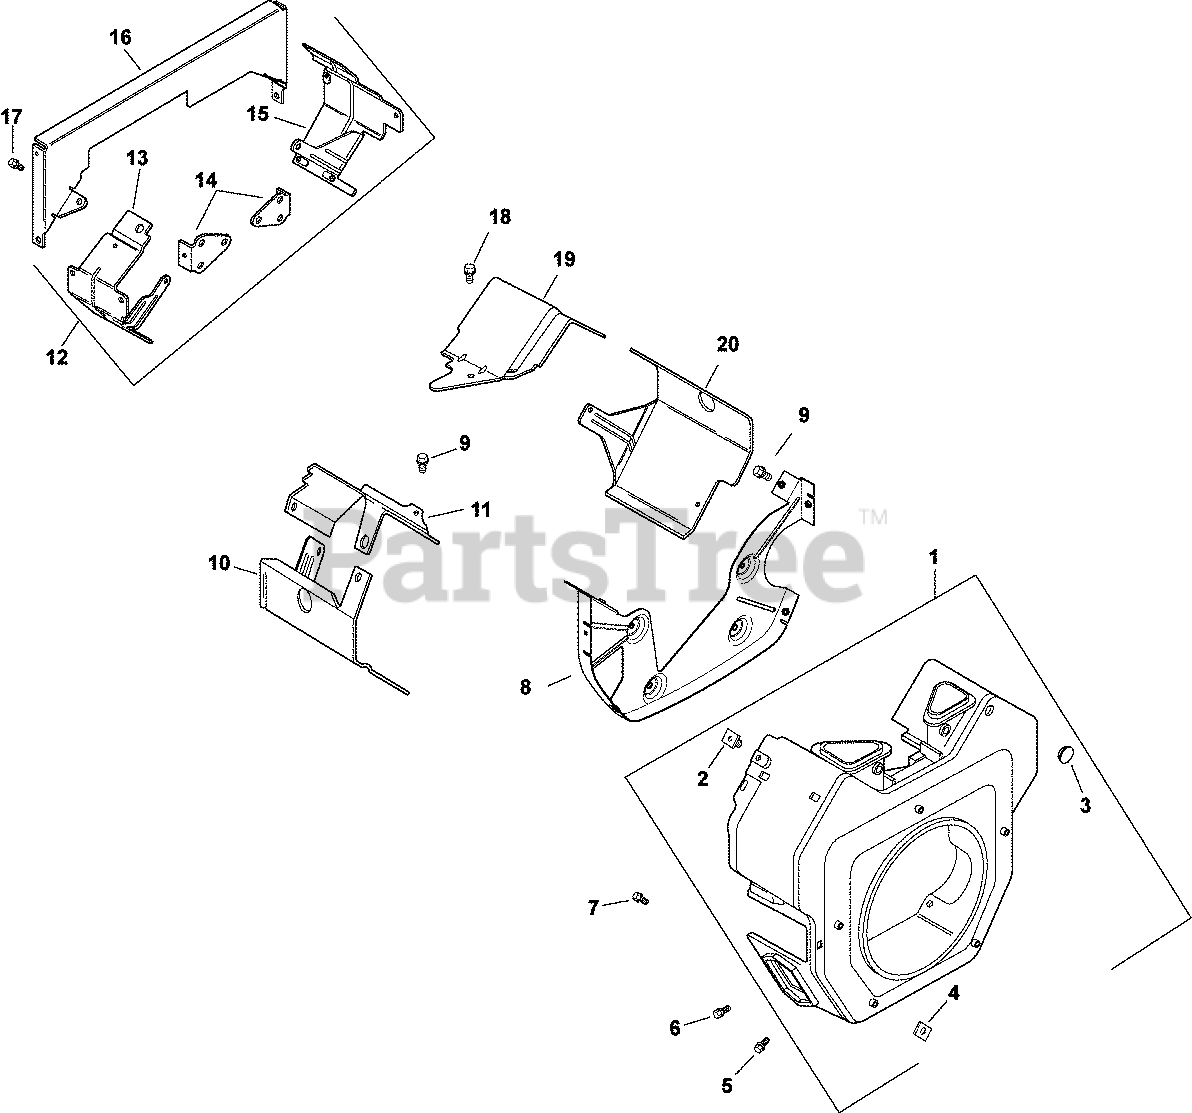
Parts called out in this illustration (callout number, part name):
1	KIT, BLOWER HOUSING ASSEMBLY USE 24 027 479-S
2	NUT, PLASTIC (KM)-USE 25 100 37-S
3	PLUG, BUTTON 9/16
4	NUT, PLASTIC
5	SCREW, HVY FLG M5X.8X16
6	SCREW,FLG THD FRM M5X0.8X16-(#25086398S)
7	SCREW, FLG THD FRM M5X.8X20-(#25086399S)
8	PLATE, BACKING-USE 24 146 59-S
9	SCREW,FLG THD FRM M6X1.0X16-(#25086397S)
10	KIT, CYL BAFFEL #2 SIDE
11	BAFFLE, VALLEY #2 SIDE-USE 24 063 94-S
12	KIT, "Q"DUCT"
13	BAFFLE, DUCTED AIR-OIL FILTER
15	BAFFLE, DUCTED AIR-STARTER
16	PLATE, BACKING
17	SCREW, FLG M6X1.0X10
18	SCREW, FLG THD FRM M5X.8X10
19	BAFFLE, VALLEY (CH)-USE 24 063 93-S
20	KIT, CYL BAFFEL #1 SIDE
